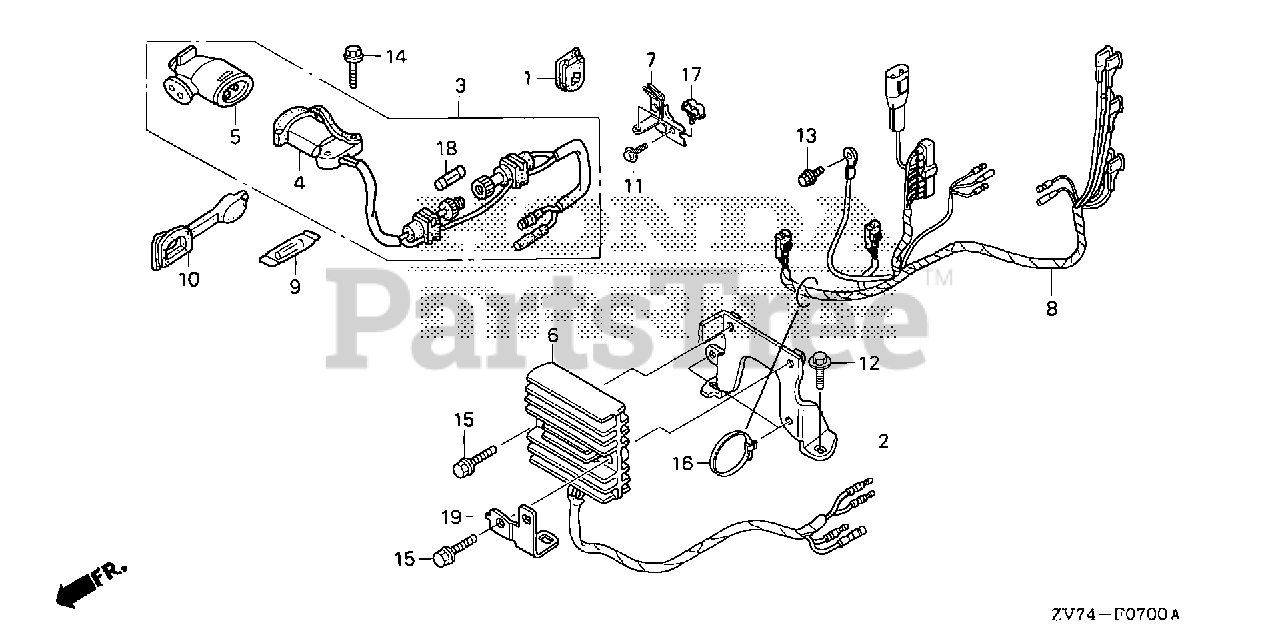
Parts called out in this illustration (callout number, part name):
1	GROMMET, WIRE
2	BRACKET, REGULATOR
3	RECEPTACLE ASSY., CHARGE
4	RECEPTACLE
5	PLUG, RECEPTACLE
6	RECTIFIER ASSY., REGULATOR (12A)
7	BRACKET, FUSE CASE
8	CABLE ASSY., IGNITION CONTROL MODULE (1) (CDI)
9	FUSE, SPARE (15A)
10	GROMMET, CASE (LOWER) (C)
11	BOLT, FLANGE (6X14) (CT200)
12	BOLT, FLANGE (6X12) (CT200)
13	BOLT, FLANGE (6X12) (CT200)
14	BOLT, FLANGE (5X22)
15	BOLT, FLANGE (6X20)
16	STRAP, CABLE (118MM) (BLACK)
17	CLIP, CORD
18	FUSE (15A)
19	BRACKET, CONNECTOR
